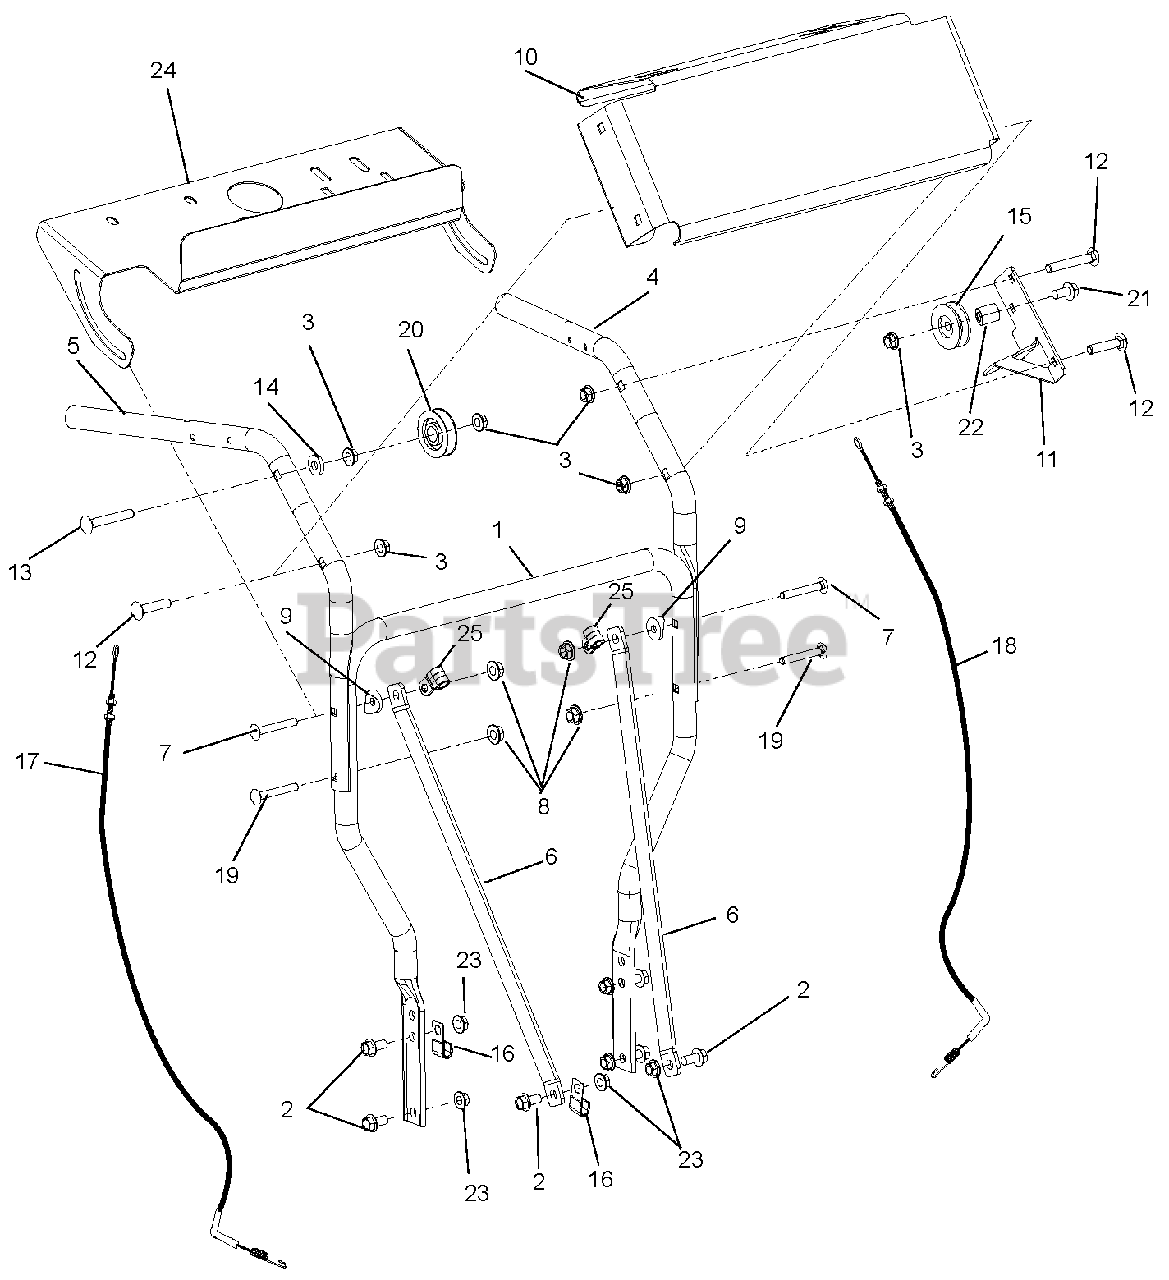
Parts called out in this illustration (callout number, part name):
1	Handlebar, Lower
2	Bolt, Screw Hex Flanged Whiz Lock Head .38-16 x .75
3	Nut, Locking Top Flange .38-16
4	Handlebar, Upper Left Hand
5	Handlebar, Upper Right Hand
6	Bracket, Handlebar Brace
7	Bolt, Round Head Square Neck .31-18 x 2.25
8	Nut, Nyloc Flange .31-18
9	Spacer, Handlebar
10	Dash, WAW
11	Mount, PTO Cable
12	Bolt, Round Head Square Neck .38-16 x 1.75
13	Bolt, Round Head Square Neck .38-16 x 2.50
14	Washer, Flat Steel .406 x 1.0 x .18
15	Idle, 3L Front Side .38 x 1.875
17	Cable, P-Brake
18	Cable, PTO
19	Bolt, Round Head Square Neck .312-18 x 1.75
20	Pulley, Cable
21	Bolt, Hex .38-16 x 2.50
22	Spacer, .437 x 1.00 x 1.23
23	Nut, Locking Center Flange .38-16
24	Bracket, Emission Component Mount (Serials 2500 and up)
25	Clamp, Cushioned Steel (Serials 2500 and up)
